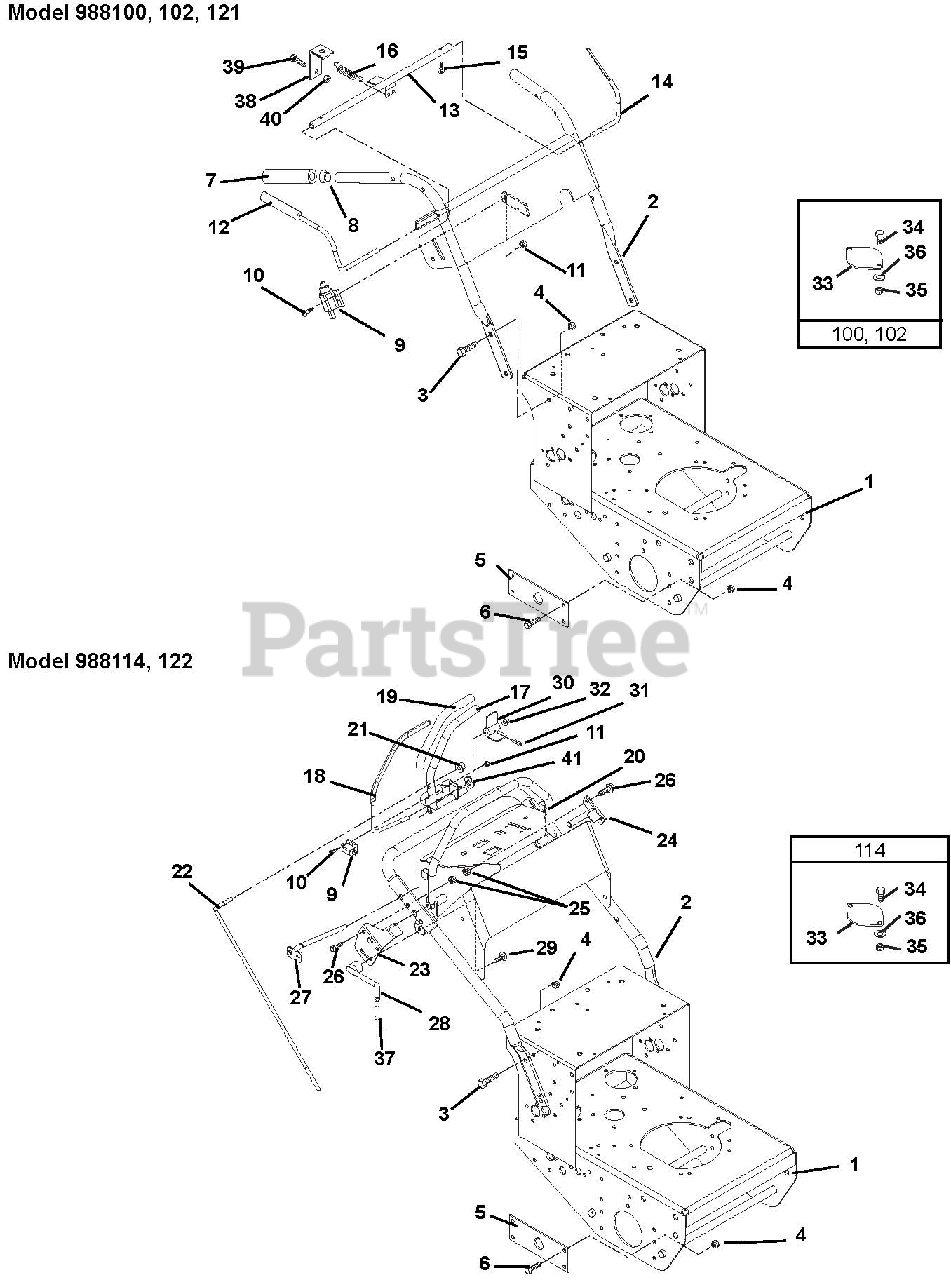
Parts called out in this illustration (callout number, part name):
1	Kit-Frame with Decals
1	Kit-Frame with Decals - 1334
2	Kit-Handlebar with Decals GR13
2	Kit-Handlebar with Decals GR15
2	Kit, Handlebar with Decals GR13/15-Pro Steer
2	Kit, Handlebar with Decals - 1334
3	Bolt-Hex .38-16 x 1.00 Grade 5
4	Nut-Locking-Nylon .38-16
5	Plate, Support
6	Bolt-Hex .38-16 x 1.00 Grade 5
7	Grip, Handlebar
8	Caplug, Handlebar
9	Switch, Double Pole
9	Switch, Interlock
10	Screw, Machine 10-24 x .75 Hex Washer Head
10	Screw-Machine 10-24 x .75 Hex Washer Head
11	Nut-Locking-Nylon 10-24 with Insert
12	Lever, Right Hand-Operator Presence
13	Weldment, Pivot Tube
14	Lever, Left Hand-Operator Presence
15	Screw-Tapping 8-32 x .50 Hex Washer Head
16	Spring-Tension .047 x .438 x 1.45
17	Weldment, Lever-Right Hand Speed Control
17	Weldment-Lever-Left Hand Speed Control
18	Lever- Operator Presence
19	Grip- Handlebar
20	Weldment- Speed Control Stop
21	Ring-Retaining-External .375 x .010
22	Rod, Steering
23	Weldment, Control Stop Limiter-Right Hand
24	Weldment, Control Stop Limiter-Left Hand
25	Nut-Locking-Top-Flange .31-18
26	Bolt-Hex .31-18 x 1.75 Grade 5
27	Weldment, Speed Control Pivot- Right Hand
27	Weldment, Speed Control Pivot- Left Hand
28	Lever- Control Stop Lock
29	Bolt-Round Head Square Neck .38-16 x .75 Grade 2
30	Actuator, Switch
31	Pin-Roll .125 x .75
32	Nut-Push .312
33	Plate, Cover
34	Bolt-Hex .38-16 x .75 Grade 5
35	Nut-Locking-Flange .375-16
36	Washer-Flat-Steel .406 x .812 x .065
37	Grip, Hand Clutch Lever
38	Bracket, Brake Link
39	Bolt, Hex .25-20 x .75 Grade 5
40	Nut, Locking Nylon .25-20
41	Washer, Wave
